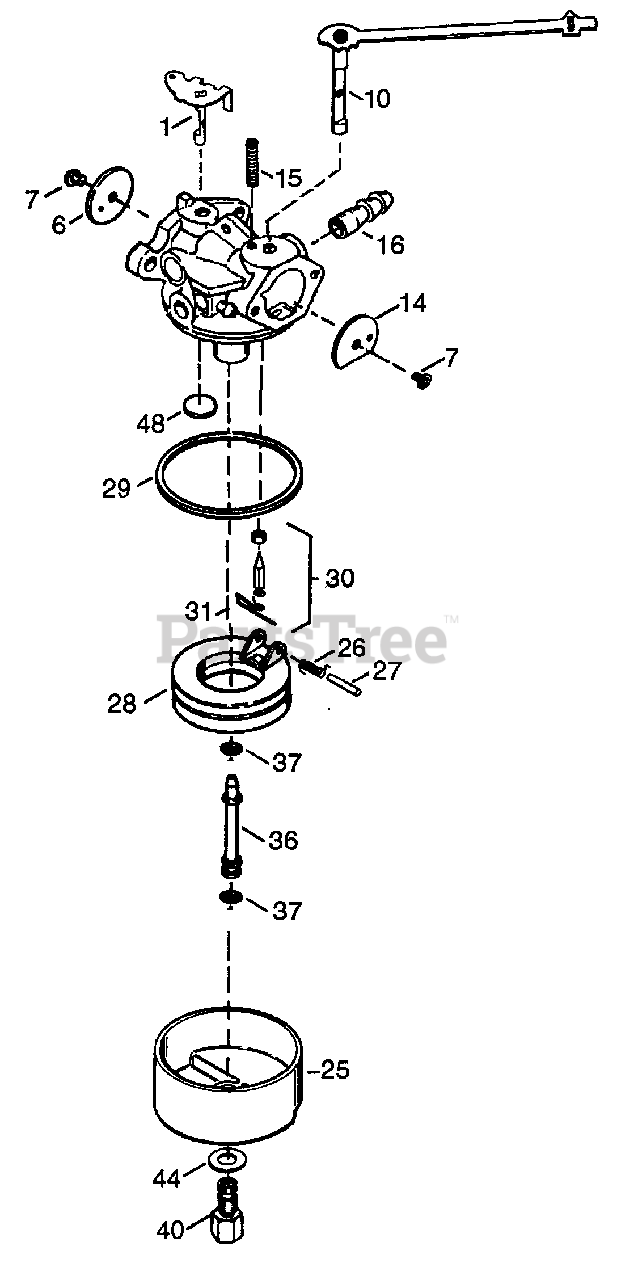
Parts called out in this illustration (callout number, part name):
1	Throttle Shaft & Lever Assy
6	Throttle Shutter
7	Shutter Screw
10	Choke Shaft & Lever Assy
14	Choke Shutter
15	Choke Positioning Spring
16	Fuel Fitting
25	Float Bowl
26	Float Dampening Spring
27	Float Shaft
28	Float
29	Float Bowl "O" Ring
30	Inlet Needle, Seat & Clip
31	Spring Clip
36	Main Nozzle Tube
37	"O" Ring, Main Nozzle Tube
40	High Speed Bowl Nut
44	Bowl Nut Washer
48	Welch Plug, Atmospheric Vent
